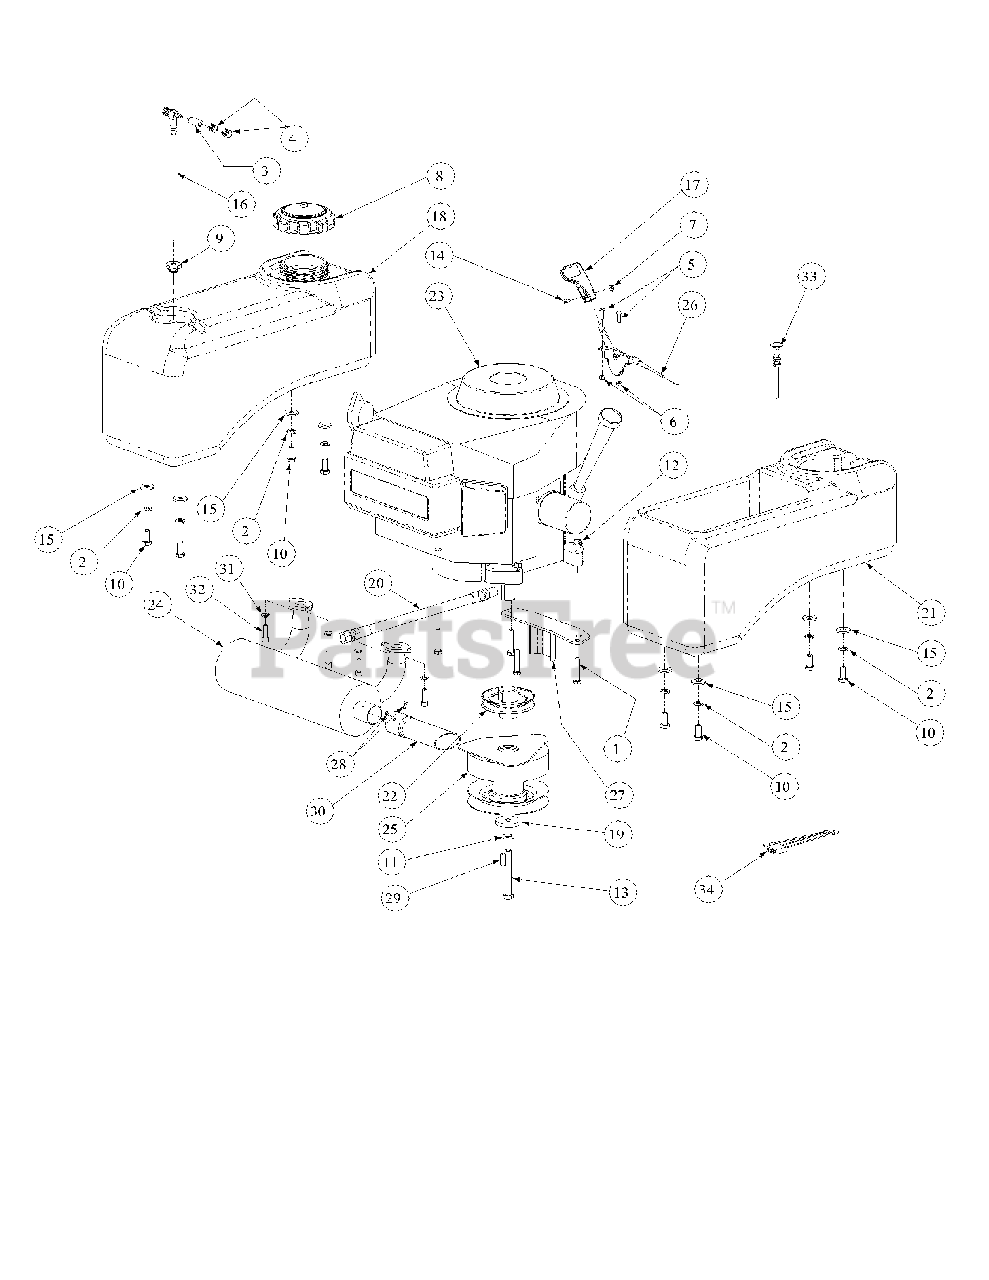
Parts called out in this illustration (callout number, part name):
1	Hex Head Cap Screw, 5/16-18 x 1-3/4
2	Lock Washer, 3/8 Zinc
3	Hose, 1/4" Fuel Line
4	Clamp, Union
5	Round Head Machine Screw, 10-32 x 3/4
6	Lock Nut, Nylon Insert, 10-32
7	Nut, w/ Star Washer
8	Fuel Cap
9	Fuel Tank Groment
10	Hex Cap Screw, 3/8-16 x .88
11	Lock Washer, 7/16
12	Lock Nut, Hex Flange, 5/16-18
13	Hex Cap Screw, 7/16-20 x 4.0
14	Machine Screw, 8-32 x .375
15	Flat Washer, .406 ID x 1.0 OD x .105
16	Fuel Pickup Fitting
17	Throttle Control Knob
18	Fuel Tank
19	Flat Washer, 7/16 ID x 1.75 OD x .250
20	Oil Drain Extension Hose
21	Utility Bin
22	Electric PTO Engine Pulley
23	18HP Twin Briggs Engine
24	Briggs Muffler
25	Ogura JD08 Electric Clutch
26	Throttle Control Cable
27	Clutch Retainer Assembly
28	Screw, 8-32 x .375, Hex Washer
29	Key, 1/4 x 1/4 x 7/8
29	Key, 1/4 x 1/4 x 2.75
30	Exhaust Pipe
31	Lock Washer, 5/16
32	Socket Head Cap Screw, 5/16-18 x 1.00
33	Choke Cable
34	Harness Adaptor
